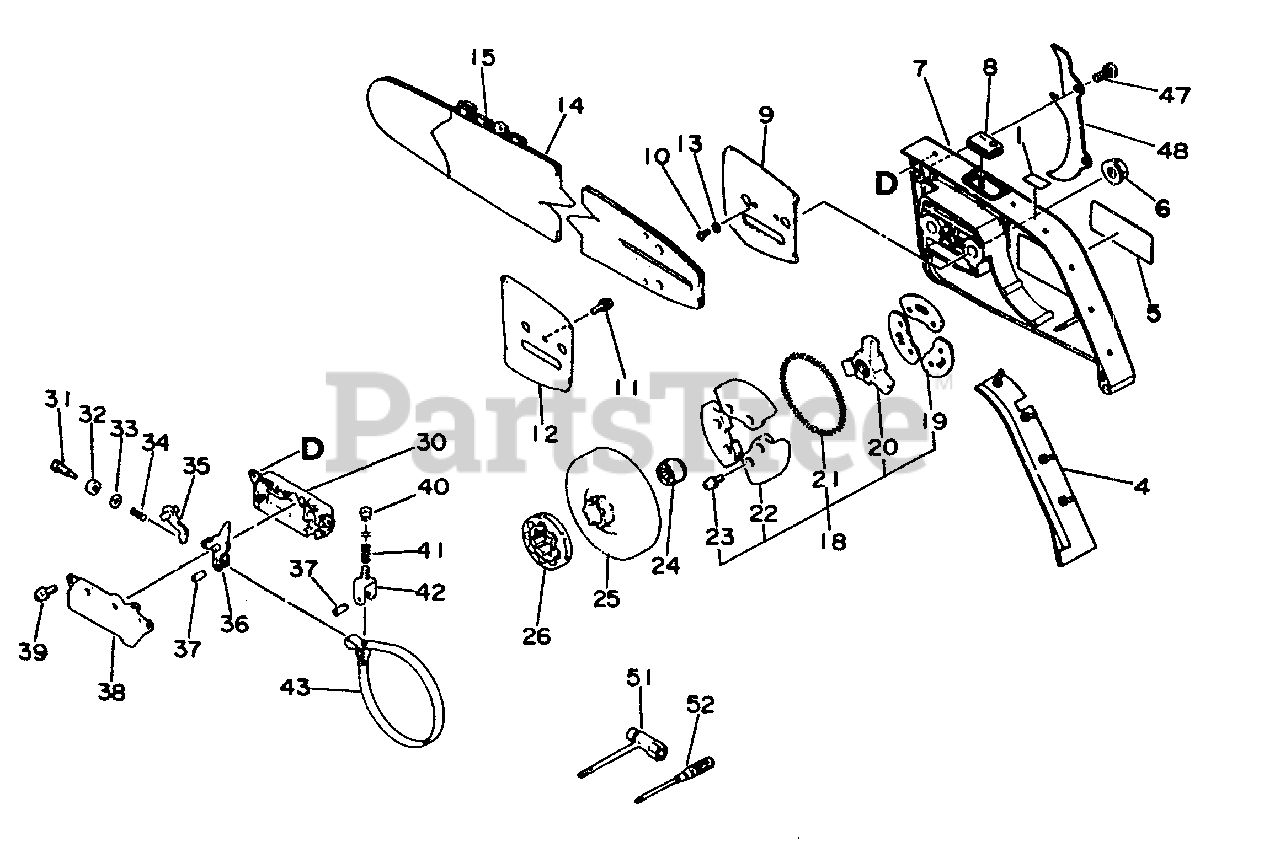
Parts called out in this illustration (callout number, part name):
1	LABEL - CAUTION
5	LABEL - ECHO
6	NUT - FLANGE
7	GUARD, SPROCKET
9	PLATE, GUIDE - OUTER
10	SCREW - 3X6
11	SCREW - 4X10
12	PLATE, GUIDE - INNER
14	GUIDE BAR
15	CHAIN, SAW
18	CLUTCH ASSY
19	PLATE, CLUTCH
20	HUB, CLUTCH
21	SPRING, CLUTCH
22	CLUTCH SHOE SET
23	SCREW - 4X8
24	BEARING, NEEDLE
25	DRUM, CLUTCH
26	SPROCKET, RIM
30	COVER, BRAKE
34	SPRING, BRAKE
35	STOPPER, BRAKE
36	LEVER, BRAKE
37	PIN - SPRING -- 4X10
38	COVER, BRAKE
39	SCREW - 4X10
42	ADJUSTER, BRAKE BAND
43	BAND, BRAKE
48	SPIKE KIT
51	T-WRENCH - 13X19mm
52	SCREWDRIVER
